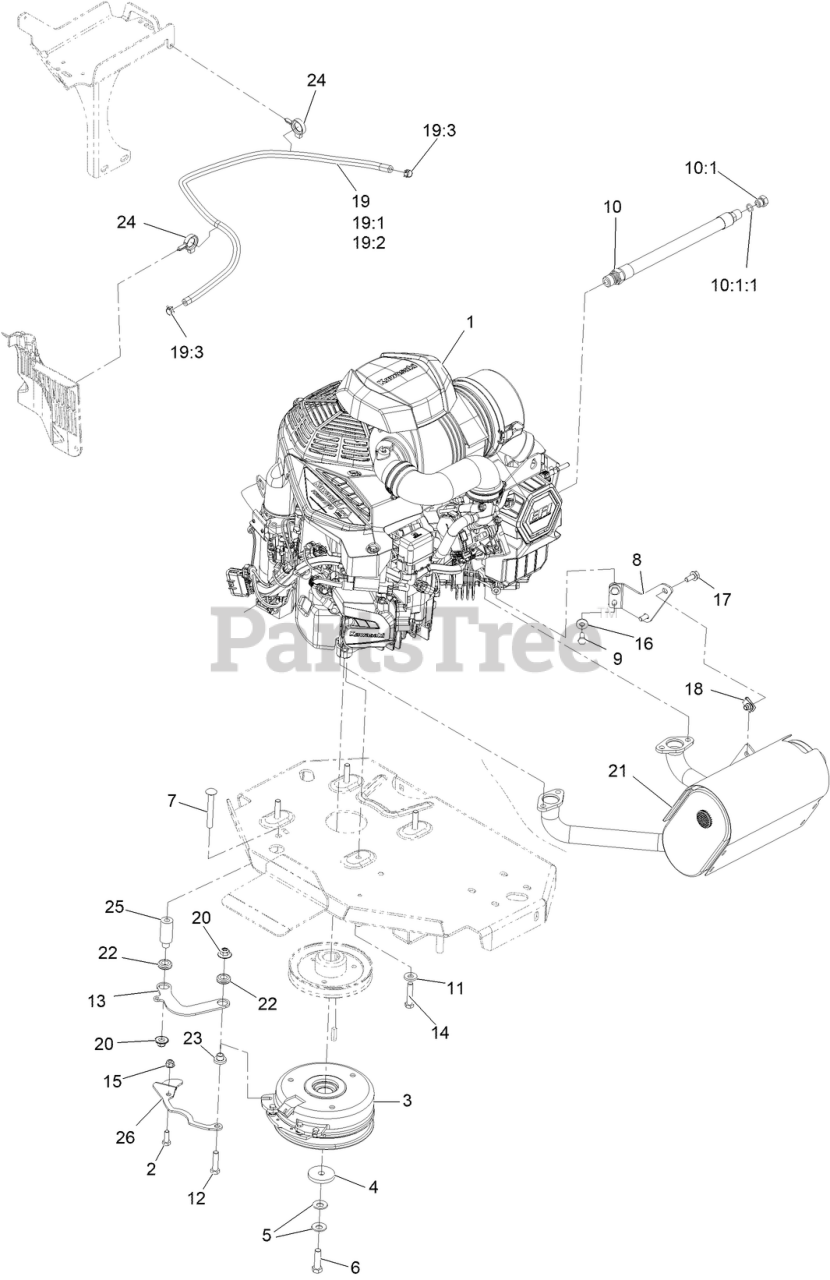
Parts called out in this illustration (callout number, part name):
2	SCREW-HH
3	CLUTCH KIT
4	WASHER-CLUTCH
5	WASHER-SPRING
6	SCREW-HH 7/16-20 X 1 1/2 W/LOCTITE
7	SCREW-CARR
8	BRACKET-MUFFLER 820KAW
9	SCREW-HH
10	ENGINE OIL DRAIN HOSE ASM
10:1	PLUG-HH
10:1:1	O-RING
11	WASHER-BELLEVILLE
12	SCREW-HH
13	LINK-ANCHOR, CLUTCH
14	SCREW-HH
15	NUT-HF, NI
16	WASHER-SPRING
17	SCREW-HHF
19	FUEL LINE ASM
19:1	HOSE-FUEL
19:2	SLEEVE-THERMAL
19:3	CLAMP-HOSE
20	Nut-Nyloc 3/8-16 Flg
21	MUFFLER-KAWASAKI FX820V
22	GROMMET-RUBBER
24	CLAMP-HOSE
26	BELT-GUIDE
